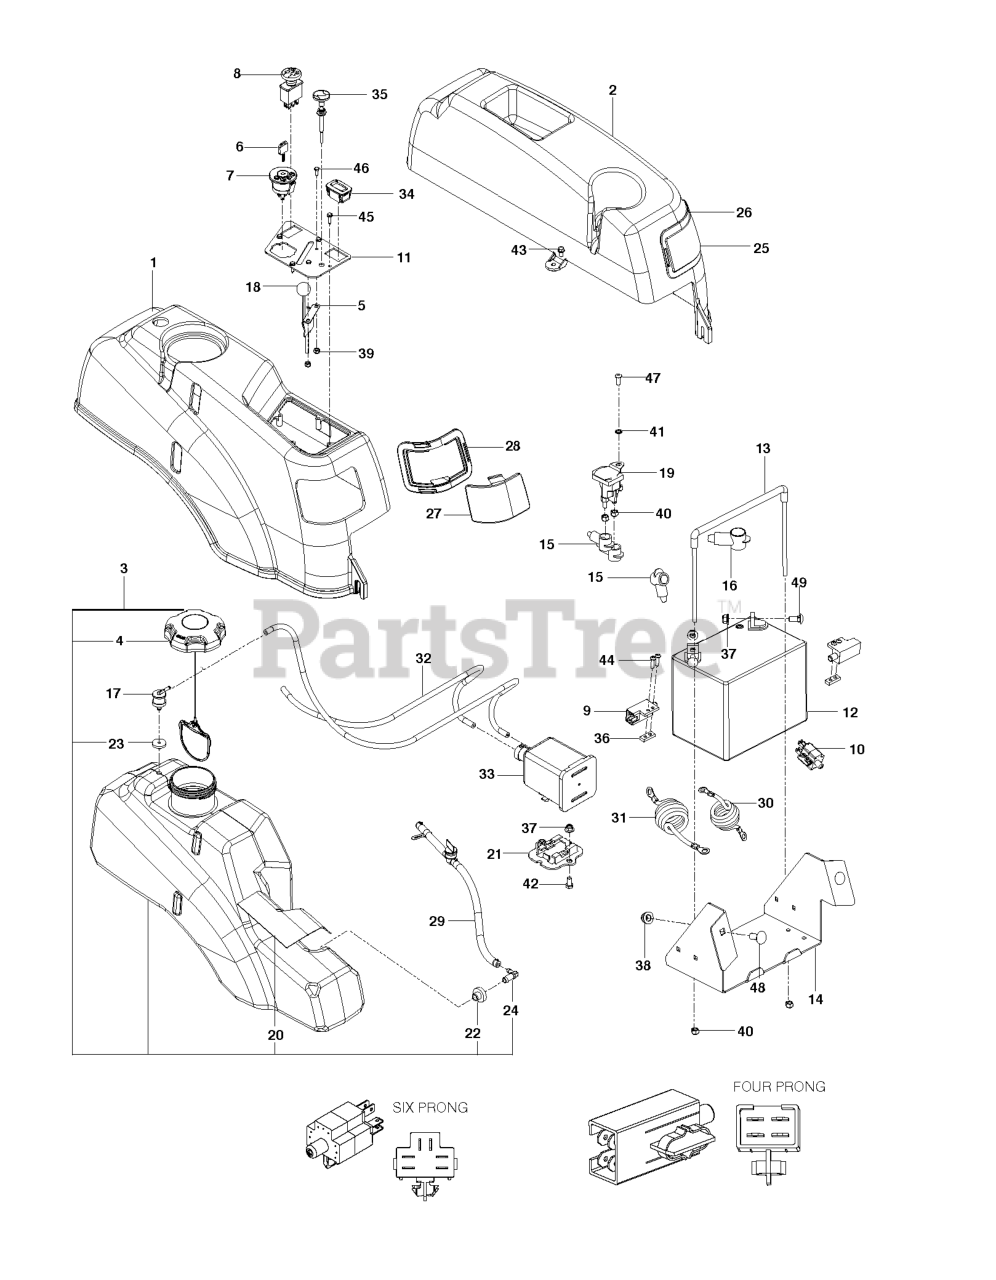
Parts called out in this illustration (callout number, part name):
1	FENDER RT, GRAY
2	FENDER, LT
3	TANK.FUEL.ASSEMBLY.LARGE
4	CAP, FUEL
5	THROTTLE CABLE
6	KEY MLD GEN DELTA
7	RP IGNITION SWITCH
8	RP SWITCH.PTO.8.TERMINAL.RED
9	SWITCH INTERLOCKT
10	SWITCH, BRAKE 3P
11	CONTROL PLATE RZ STD X431
12	BATTERY, 12 V 330 AMP
13	BATTERY TIE DOWN ASSEMBLY
14	BOX, BATTERY, BLACK
15	TERMINAL COVER-SM
17	VALVE.FUEL.CHECK
18	KNOB.ROUND.BALL.BLACK
18	FUEL VALVE
19	SOLENOID.W/BRASS.PLUNGER
20	SHIELD, HEAT
21	BRACKET, CANISTER
22	RUBBER GROMMET
23	GROMMET, CHECK VALVE
24	STEM, FUEL TANK
25	LENS, COLORED LEFT
26	LEFT HEADLIGHT RIM GREY
27	LENS, COLORED RIGHT
28	RT HEADLIGHT RIM GREY
29	ASSEMBLY, FUEL LINE, KAW
30	CABLE POSITIVE, LONG
31	BATTERY CABLE, NEGATIVE
32	FUEL LINE 33"
33	WASHER 1/4 INT TOOTH
34	GUAGE.SRVCMNDR.HRMTR.
35	CHOKE CABLE
36	TAPPED PLATE
37	5/16-18 NYLOC FLANGE NUT
38	NUT 3/8-16 HEX FLG NYLOC ZD
39	NUT 10-24 NYLOC
40	LOCKNUT.NYLOC.1/4-20
41	WASHER 1/4 INT TOOTH
42	HCS 5/16-18 X 5/8 GR 5 ZD
43	SCREW
44	SCR #10-24 X .75 SKT HD BLK
45	SCR #10-12X3/4 HEX WAS HD ZD
46	HCS #10-24 X 1/2
47	SCR 1/4-20 X 5/8 BTN SKT HD ZD
48	BOLT D
49	RP BOLT 5/16-18 X3/4 ZN/YEL GR
